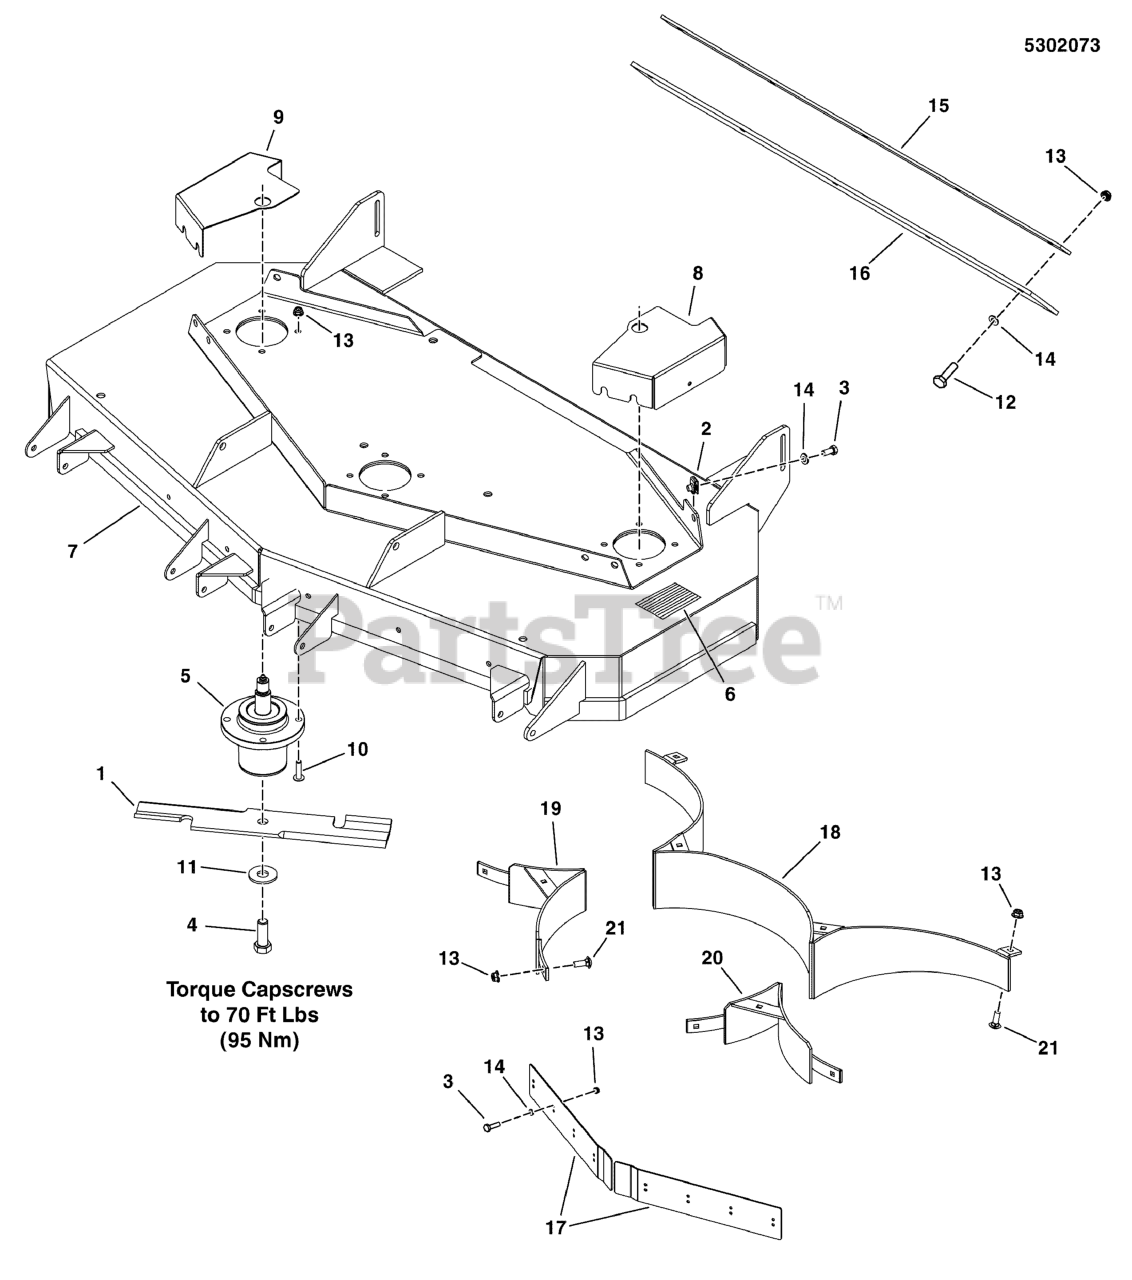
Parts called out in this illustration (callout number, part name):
1	BLADE, 18, SET OF THREE
2	BODY CLIP, 5/16-18-7GA MATERIAL
3	BOLT, 5/16-18 X 3/4 GD5
4	BOLT, 5/8-11 X 1-3/4 GD8
5	ASSM, SPINDLE, LOW PROFILE
6	SAFETY WALK, 4.00 X 7.50
7	DECK SHELL W/ DECALS, 52RD, S175X
8	GUARD, 52" DECK, IS2000 - LH - RED
9	GUARD, 52" DECK, IS2000 - RH - RED
10	BOLT, 5/16-18 X 1 1/4 FLANGE
11	WASHER, 5/8 GRADE 8, YZ
12	BOLT, 5/16-18 X 1-1/4 GD5 YZ
13	NUT, 5/16-18 HEX NYLOCK FLANGE
14	WASHER, 5/16" SAE
15	PLATE, FLAP RETAINER, 2000 RD - BLK
16	FLAP, 2000 REAR DISCHARGE
17	BAFFLES. FRONT DISCHARGE, 52 YAN - BLK
18	WELD, REAR BAFFLE, 52 RD - BLK
19	WELD, FRT-RGHT BAFFLE, 52 RD - BLK
20	WELD, FRT-LFT BAFFLE, 52 RD - BLK
21	BOLT, 5/16-18 X 1, CARRIAGE
